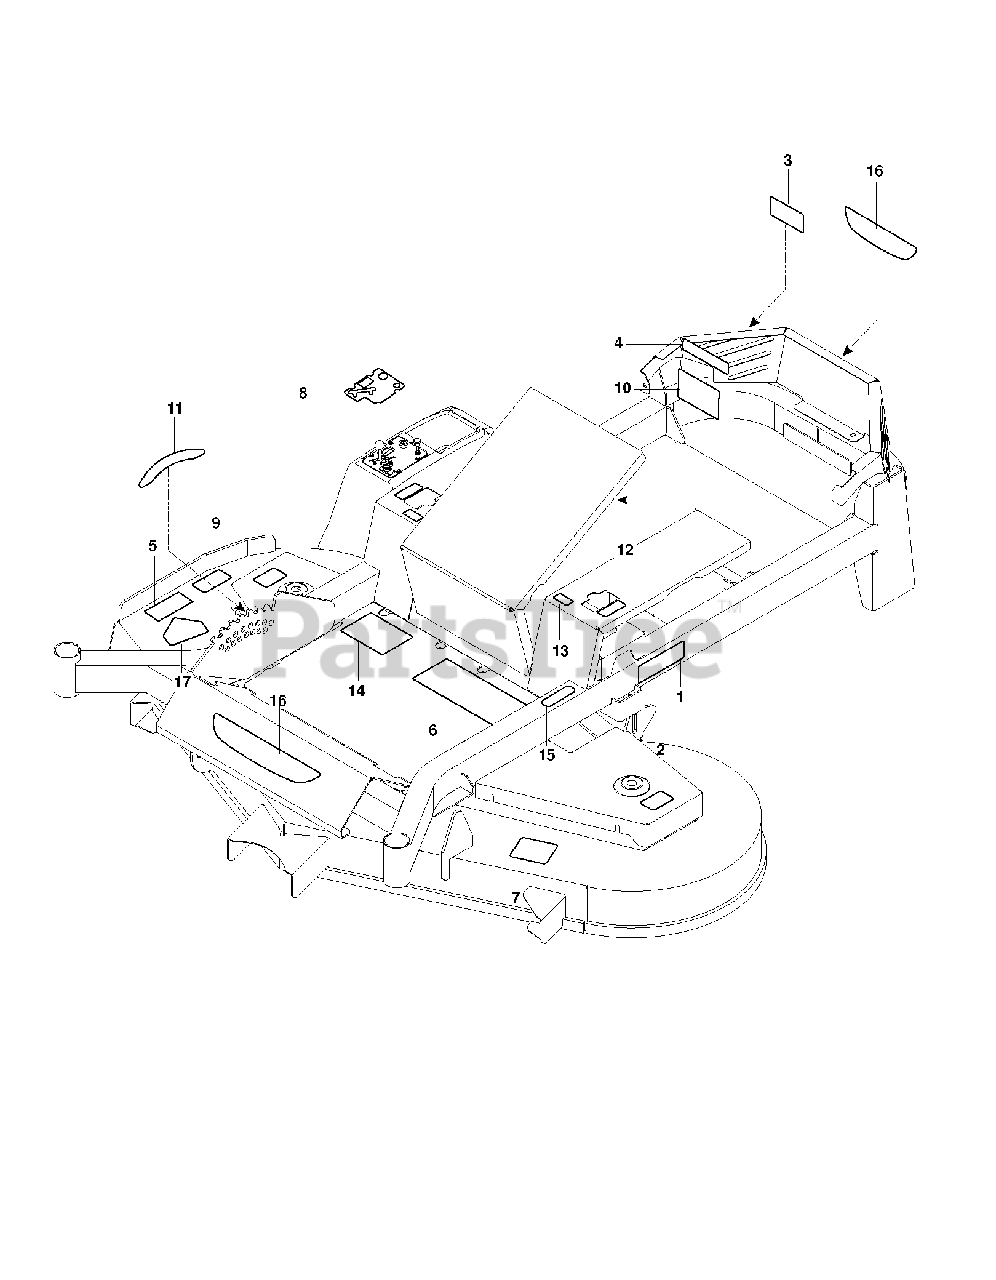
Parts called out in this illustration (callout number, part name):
2	No Step Decal
3	DECAL, BELT DRIVE
4	DECAL, BATTERY
5	DECAL, EURO SEVERING
6	DECAL, WARNING
7	DECAL, BELT ROUTING
9	Deflector Shield Warning Decal
10	DECAL, SERVICE
17	DECAL, DECK DEFLECTOR, WARNING
